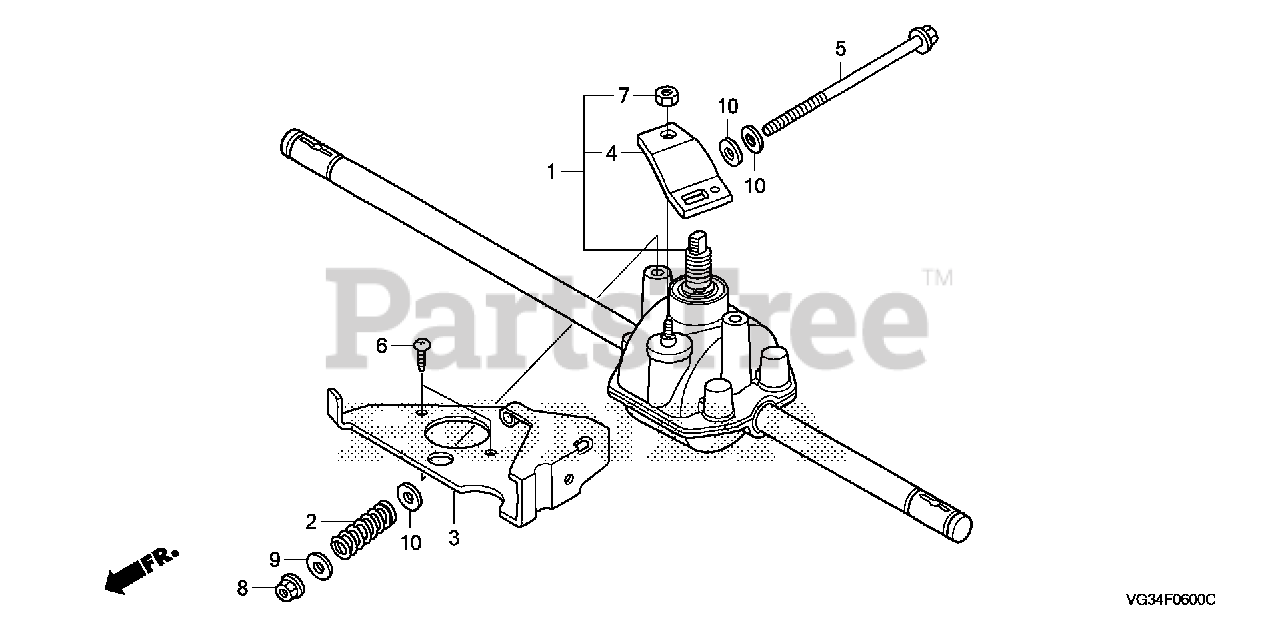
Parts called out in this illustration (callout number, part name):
1	TRANSMISSION ASSY.
2	SPRING, BELT TENSIONER
3	HOLDER, WIRE
4	ARM, CLUTCH
5	BOLT, FLANGE (6X140)
6	SCREW, TAPPING (1/4")
9	WASHER, PLAIN (6MM)
10	WASHER, PLAIN (8MM)
